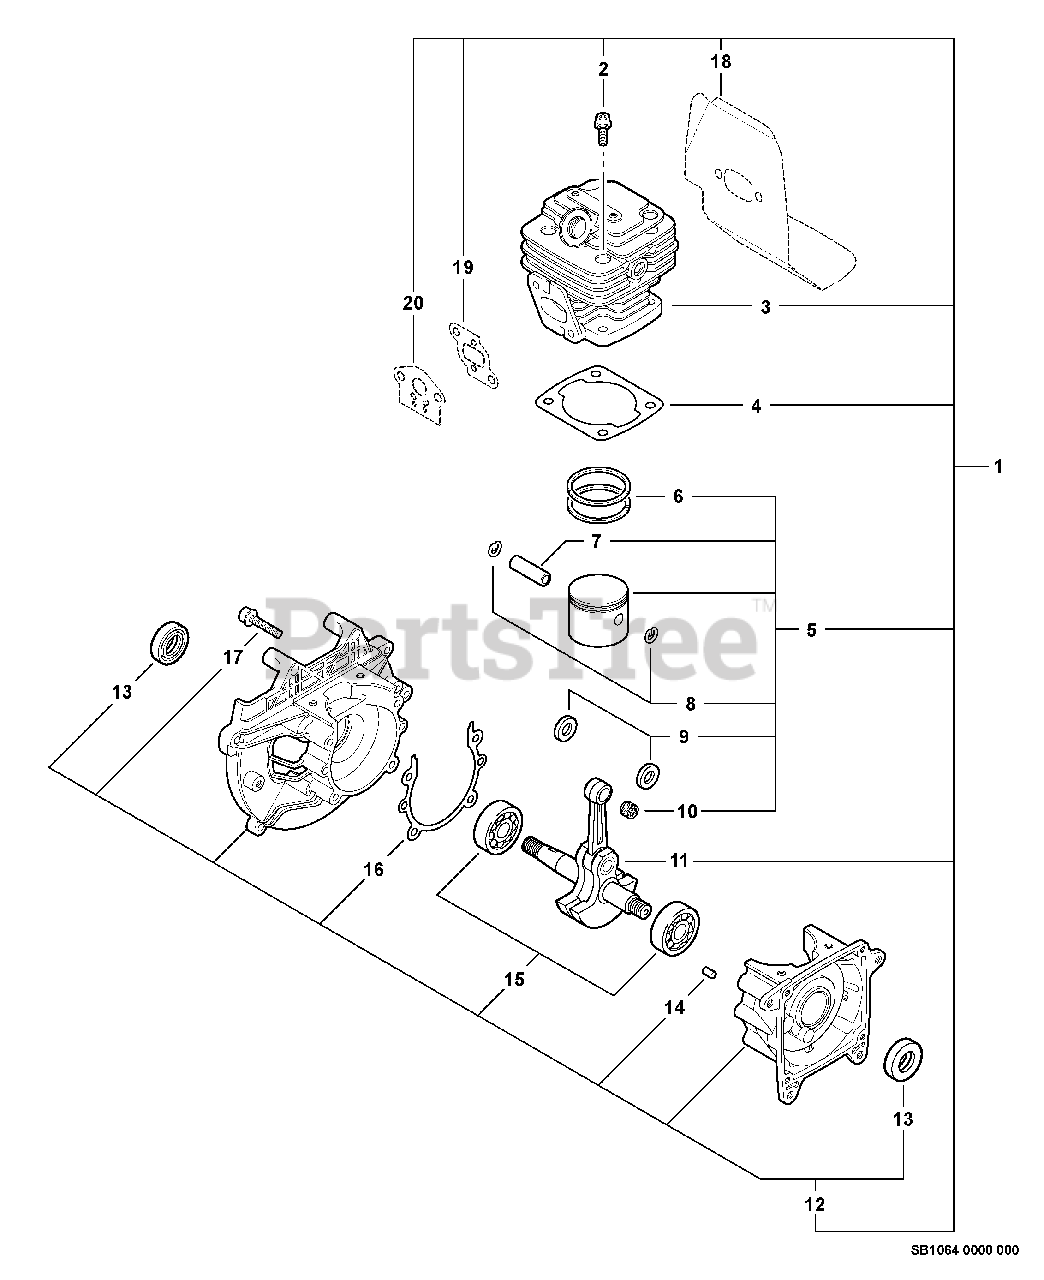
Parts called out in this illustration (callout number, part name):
1	SHORT BLOCK -- SB1064
2	SCREW - 5X20
3	CYLINDER
4	GASKET, CYLINDER
5	PISTON KIT
6	RING, PISTON
7	PIN, PISTON
8	RING, RETAINING
9	SPACER, PISTON
10	BEARING, NEEDLE
11	CRANKSHAFT ASSY
12	CRANKCASE KIT
13	SEAL, OIL
14	PIN - LOCATING
15	BEARING, BALL - 6201
16	GASKET, CRANKCASE
17	SCREW - 5X30
18	SHIELD, EXHAUST
19	GASKET, INTAKE
20	GASKET, INTAKE
